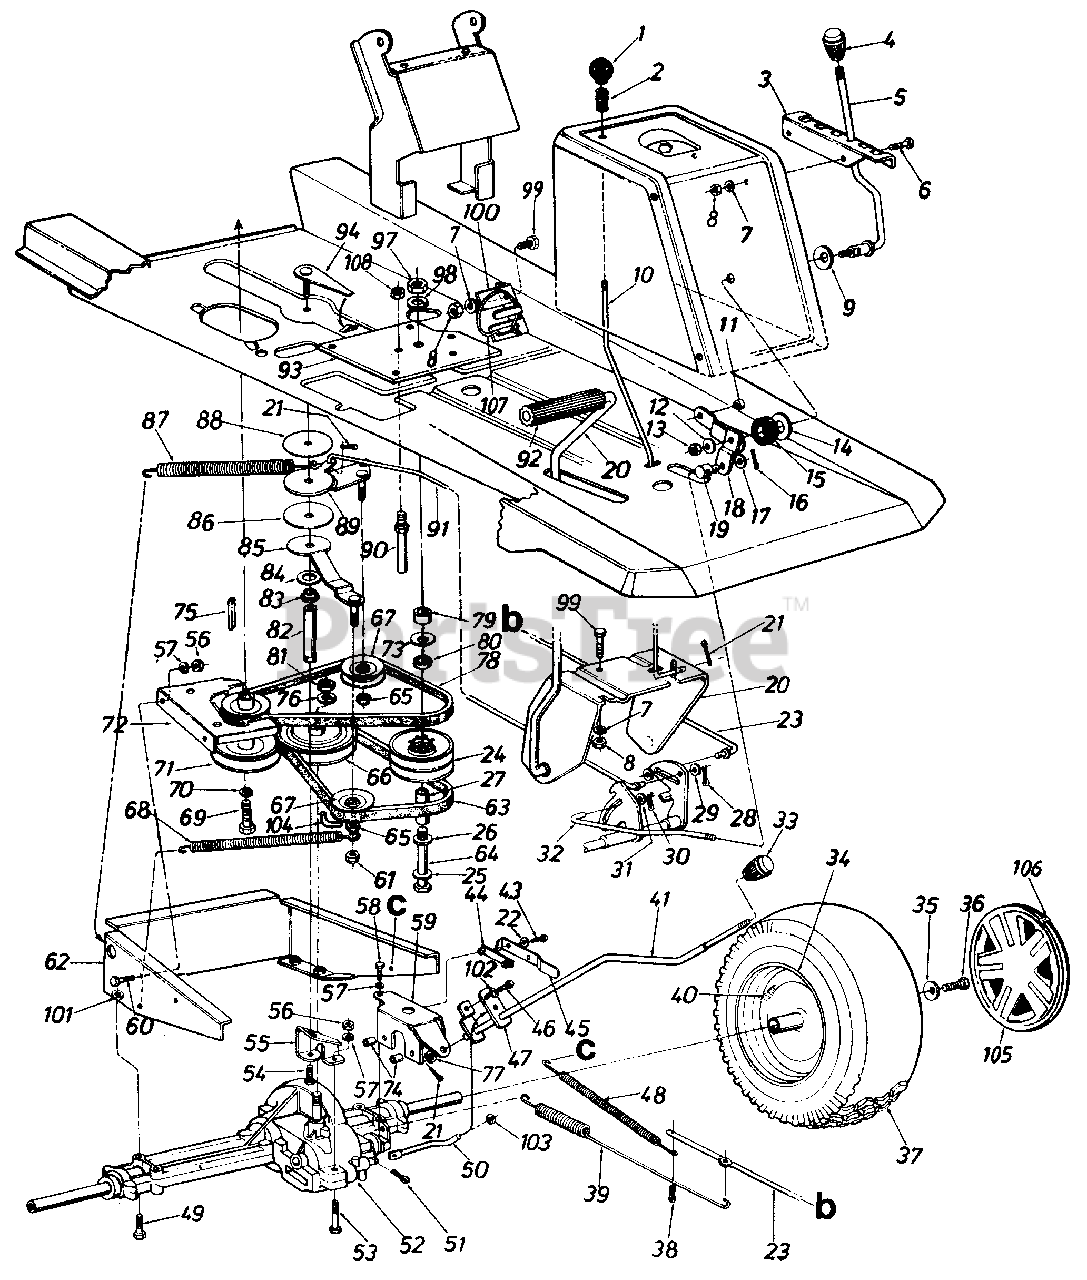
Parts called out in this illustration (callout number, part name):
1	Ball Knob 1/4-20 Thd. 1.25"
2	Compression Spring
5	Speed Control Lever
6	Truss Mach. Scr. 5/16-18 x .75" Lg.
7	L-Wash. 5/16" I.D.
8	Hex Nut 5/16-18 Thd.
9	Bell-Wash. .345" I.D. x .88"
10	Brake Locking Rod
12	Bell-Wash. .345" I.D. x .08"
13	Hex Cent. L-Nut 5/16-18 Thd.
14	Fl-Wash. .531" I.D. x 1.25" O.D.
15	Rubber Washer
16	Intern. Cotter Pin 1/2" Dia.
17	Fl-Wash. .34" I.D. x .68" O.D.
18	Speed Control Lever Brkt. Ass'y.
19	Ferrule - Engagement
20	Clutch/Brake Pedal Ass'y.
21	Cotter Pin 3/32" Dia. x .75"
22	Plastic Washer
23	Brake Rod
24	Variable Speed Pulley Ass'y.
25	Fl-Wash. .4" I.D. x 1.25" O.D.
26	Thrust Brg. 1.25" O.D. x .56" I.D.
27	Spacer Sleeve 2.71"
28	Cotter Pin 1/8" Dia. x 1.25"
29	Fl-Wash. .34" I.D. x .60" O.D.
30	Intern. Cot-Pin 5/16" Dia.
31	Fl-Wash. .34" I.D. x .60" O.D.
32	Speed Control Link
33	Shift Knob
35	Bell-Wash. .345" I.D. x .88"
36	Hex L-Bolt 5/16-24 x .75" Lg.
38	Cotter Pin 1/8" Dia. x 1.25"
39	Extension Spring 17.0" Lg.
40	Air Valve
44	Insulator Nut
45	Spring Switch
46	Hex Bolt 1/4-20 x .50" Lg.
47	Shift Lever Adjusting Link
48	Ext. Spring 8-1/4" Lg.
49	Hex Bolt 5/16-18 x 2.5" Lg.
50	Shift Rod
51	Intern. Cotter Pin
52	Transaxle
53	Hex Bolt 1/4-20 x 1.75" Lg.
54	Hex Bolt 3/8-24 x .75" Lg.
57	L-Wash. 1/4" I.D.
58	Self-Tap Mach. Scr. Type "C" 1/4-20 x 1.37" Lg.
59	Shift Lever Support Brkt.
60	Hex Bolt 1/4-20 x 1.00" Lg.
61	Hex L-Nut 3/8-24 Thd.
64	Hex Bolt 3/8-16 x 4.5" Lg.
65	Hex Ins. L-Nut 3/8-24 Thd.
66	V-Pulley
67	V-Belt Idler .38" I.D. x 3.06"
68	Ext. Spring .50" O.D. x 6.37"
69	Hex Bolt 7/16-20 x 1.00" Lg.
70	L-Wash. 7/16" I.D.
71	Engine Pulley
72	Upper Eng. Belt Guard
73	Bell-Wash. .4" I.D. x 1.12" O.D.
74	Spacer .256" I.D. x .50" O.D.
75	Sq.-Key 1/4" x 2.00" Lg.
76	Bell-Wash. .567" I.D. x 1.125"
77	Fl-Wash. .469" I.D. x .88" O.D.
78	V-Belt
79	Spacer 1.00" x .380" O.D.
80	Thrust Wash. .56" I.D. x 1.25" O.D.
81	Hex Jam Nut 9/16-18 Thd.
82	Torque Rod
83	Flange Bearing .378
84	Fl-Wash. .640" I.D. x 1.24"
85	Idler Bracket Ass'y.
86	Thrust Wash. .635" I.D.
87	Extension Spring 7.58" Lg.
88	Thrust Wash. .385" I.D.
89	Idler Bracket Ass'y. For Clutch
90	Belt Guard Pin 3/8-16 x 2.75" Lg.
91	Clutch Rod
92	Foot Pad
98	L-Wash. 3/8 Heavy Duty
99	Hex Bolt 5/16-18 x .75" Lg.
100	Speed Control Rod Brkt.
101	Hex Sems Nut 5/16-18 Thd.
102	Bell-Wash. .265" I.D. x .75" O.D.
103	Push on Retaining Ring
104	Belt Guard
105	Hub Cap - Beige
106	Spring Clip
107	Comp. Spring Clip
108	Hex Top L-Jam Nut 3/8-16 Thd.
